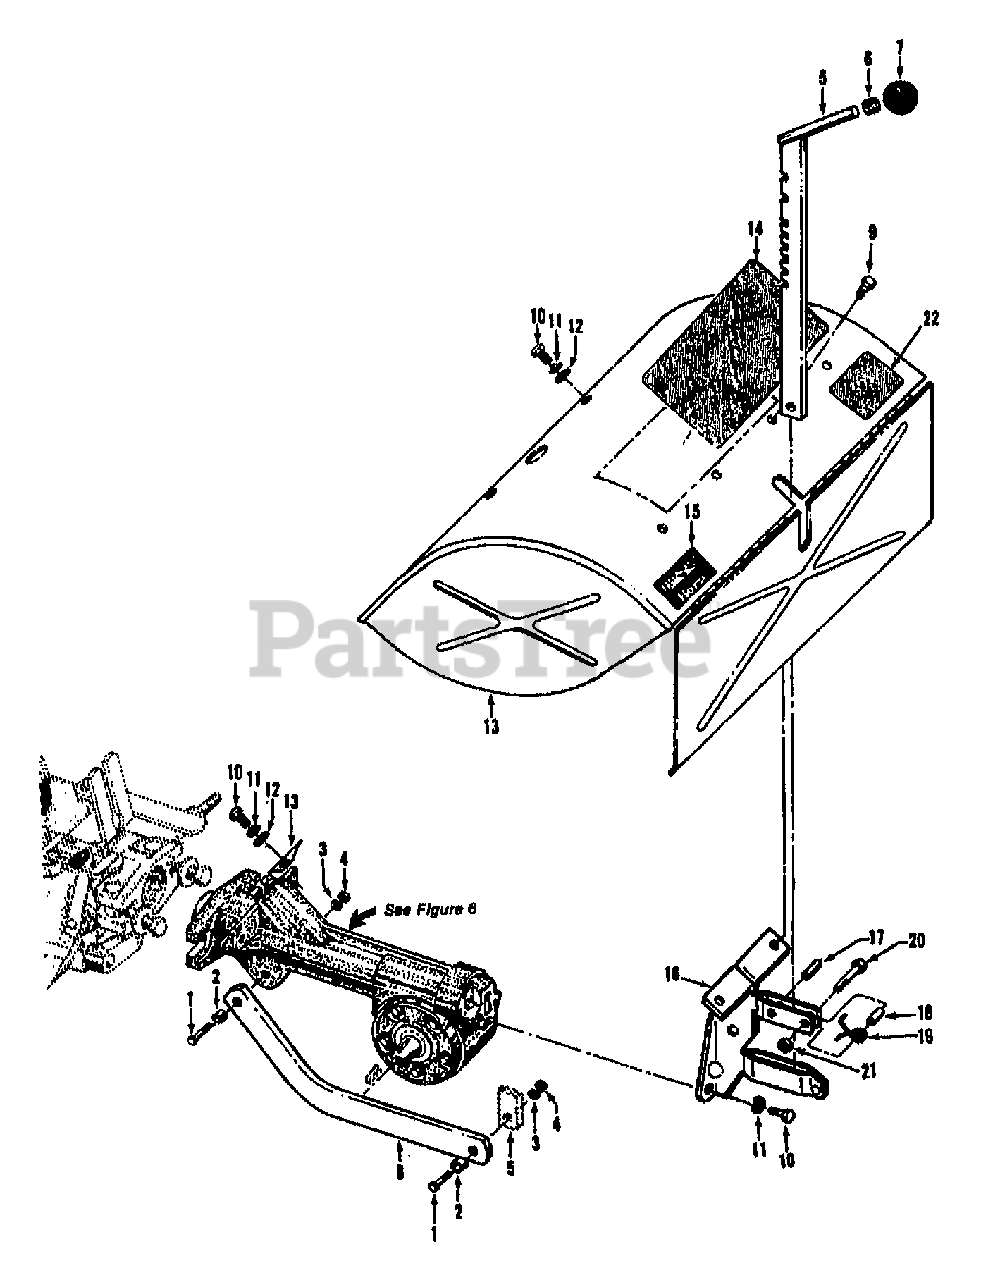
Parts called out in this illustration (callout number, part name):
1	SCR-HH 3/8-16X1.25
2	BUSHING-.5X.375X.3
3	WASHER-LK .375 @ DEPL
4	NUT-HEX 3/8-16 ZP
5	DEPTH REGULATOR W/KNOB (INCL., 7 & 6)
6	RING-TOLERANCE .5325 ID
7	KNOB-CONTROL
8	BAR-DRAG RED
9	SCR-HWH 1/4-20 X .5 STH
10	SCR-HHC 5/16-18X.75 GR 5 ZP
11	WASHER-LK .312 ZP
12	WASHER-#1.125X.344 ZP
13	HOOD W/DECALS OPC SERVICE (INCL. 14,15 & 22)
14	DECAL-HOOD INST OPC
15	DECAL-HORSE LOGO OPC (HORSE)
16	BRKT W/ROLL PIN (9308) (INCL. 17)
17	PIN-ROLL .25 X 1
18	SPACER-.250X.343X.375
19	SPRING-TORSION
20	SCR-HH 1/4-20X1.0
21	NUT-LK 1/4-20
22	DECAL-TINE WARN SM FRAME
